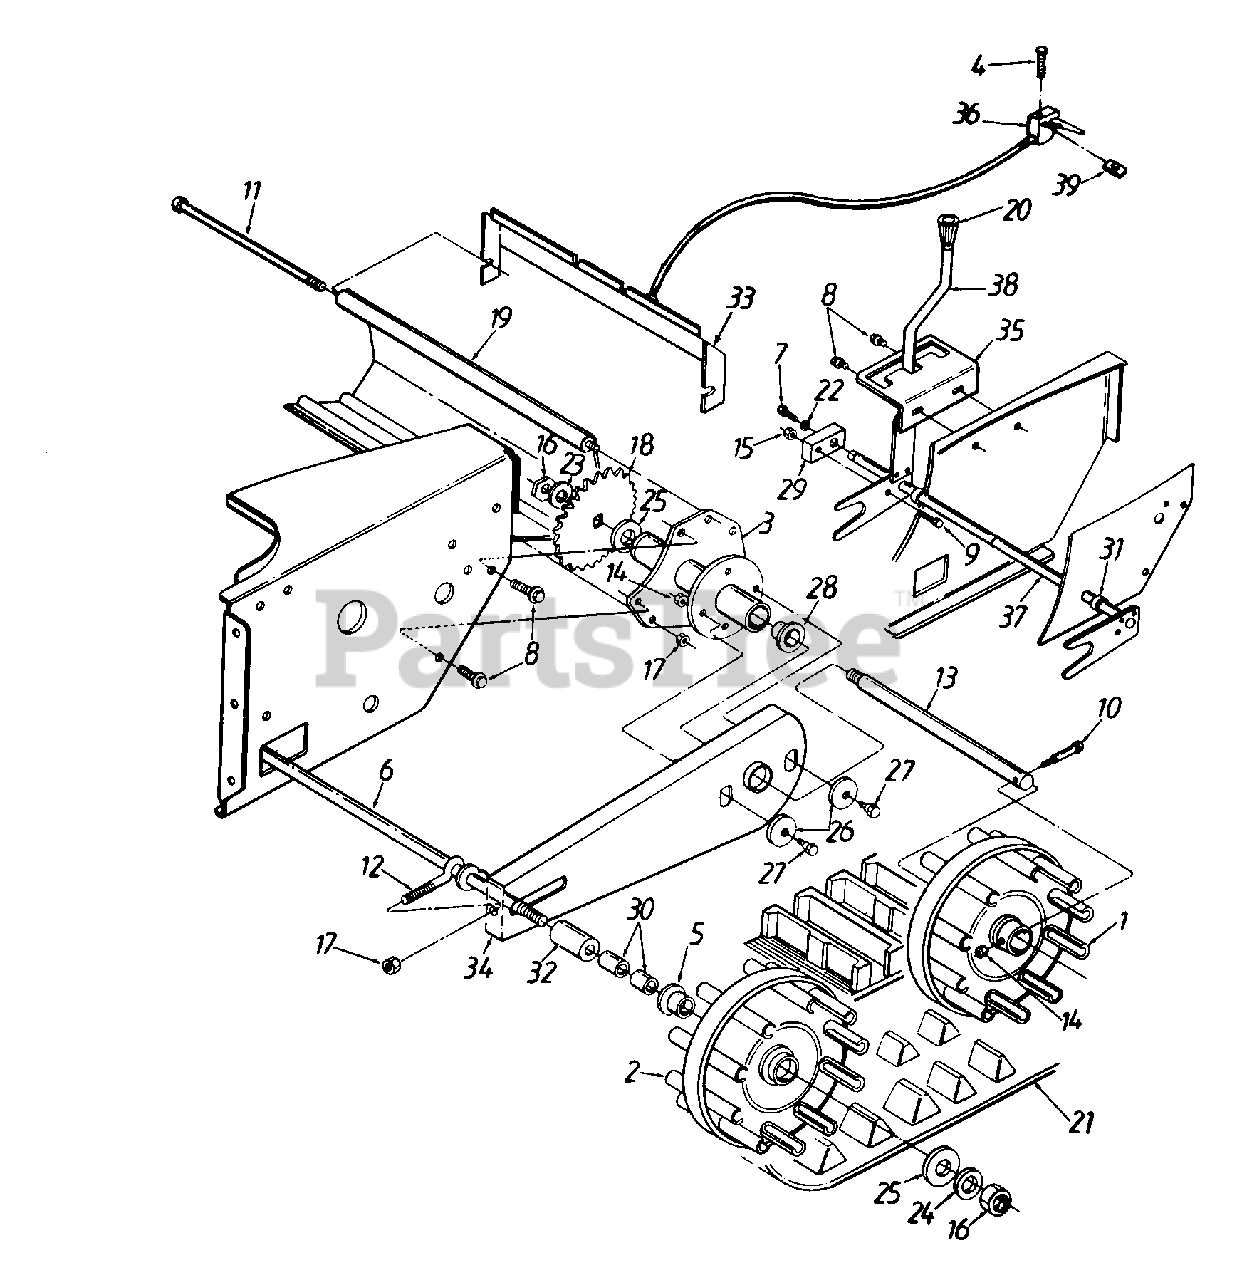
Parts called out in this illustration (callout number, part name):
1	Drive Wheel Ass'y.
2	Idler Wheel Ass'y.
3	Track Hub Ass'y.
4	Oval C-Sunk Hd. Scr. 10-24 x 1.375" Lg.
5	Flange Bearing 3/4" I.D. x 15/16" Lg.
6	Idler Axle Ass'y.
7	Hex Bolt 5/16-24 x .75" Lg.
8	Hex Wash. TT-Tap Scr. 5/16-18 x .62" Lg.
9	Hex Bolt 3/8-24 x 1.5" Lg. (Special)
10	Bolt 5/16-18 x 1.5" Lg.
11	Hex Bolt Ass'y. 5/16-18 x 9.81" Lg.
12	Eyebolt 5/16-18 x 3" Lg.
13	Drive Axle
14	Hex Cent. L-Nut 5/16-18 Thd.
15	Hex Cent. L-Nut 3/8-24 Thd.
16	Hex Ins. Jam L-Nut 1/2-20 Thd.
17	Hex L-Nut 5/16-18 Thd.
18	24 Tooth Sprocket
19	Track Housing
21	Snow Track
22	L-Wash. 5/16" I.D.
23	Bell-Wash. .515" I.D. x 1.14" O.D.
24	Fl-Wash. .531" I.D. x 1.25" O.D.
25	Fl-Wash. .793" I.D. x 1.24" O.D.
26	Fl-Wash. 3/8" I.D. x 7/16" O.D.
27	Shld. Bolt .437" Dia. x .162
28	Flange Bearing 3/4" I.D. x 15/16" Lg.
29	Lift Shaft Drive
30	Spacer .5" I.D. x .78" Lg.
31	Spacer .628" I.D. x .5" Lg.
32	Spacer .51" I.D. x 1.34" Lg.
36	Track Steer Cable w/Trigger
39	Flat Weld Nut #10-24 Thd.
